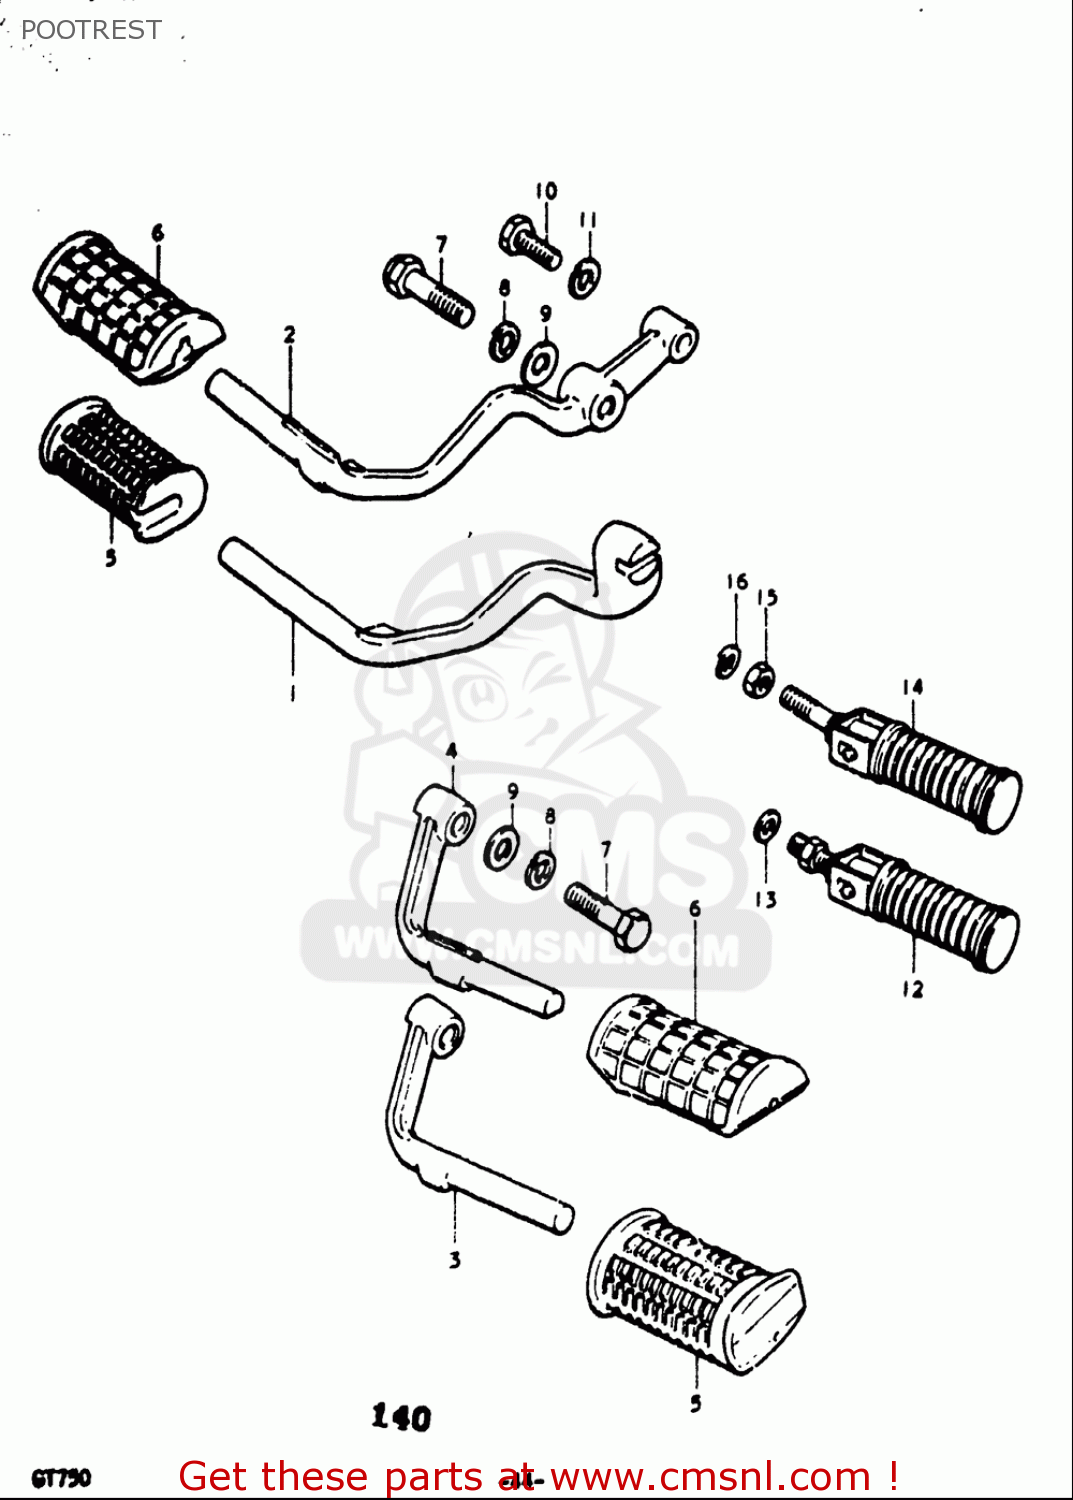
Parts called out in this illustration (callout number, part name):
2	BAR,FRONT FOOTREST,RIGHT
6	RUBBER,FR FOOTREST
7	BOLT(12X45)
8	WASHER,LOCK
9	WASHER
10	BOLT
11	WASHER,LOCK
12	FOOTREST ASSY,PILLION
13	WASHER
15	NUT
16	WASHER,LOCK
